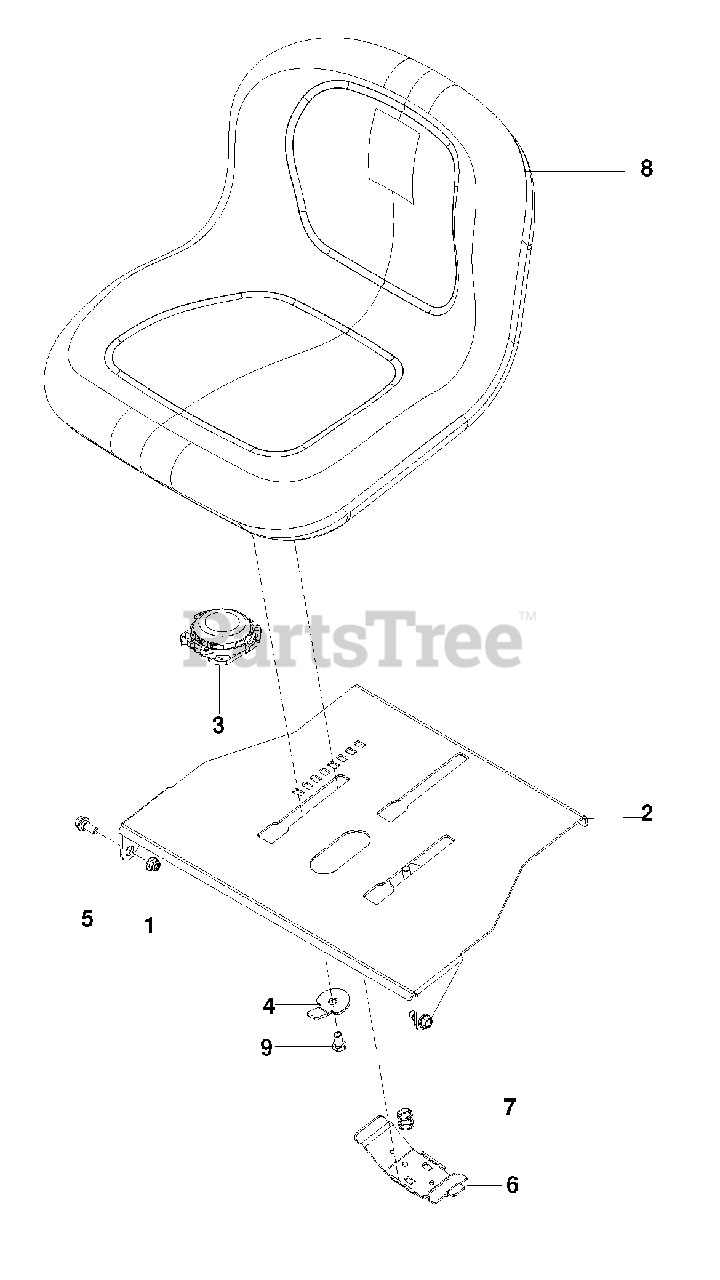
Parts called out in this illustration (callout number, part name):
1	NUT5/16-18FLANGENYLOC
2	PLATE,SEATORG
3	SWITCH,SEATN/C
5	BOLT5/16-SHOULDER
6	HANDLE,SEATSLIDE
7	SPRING,SEATSLIDE
8	SEAT
9	HCS3/8-16x5/8
